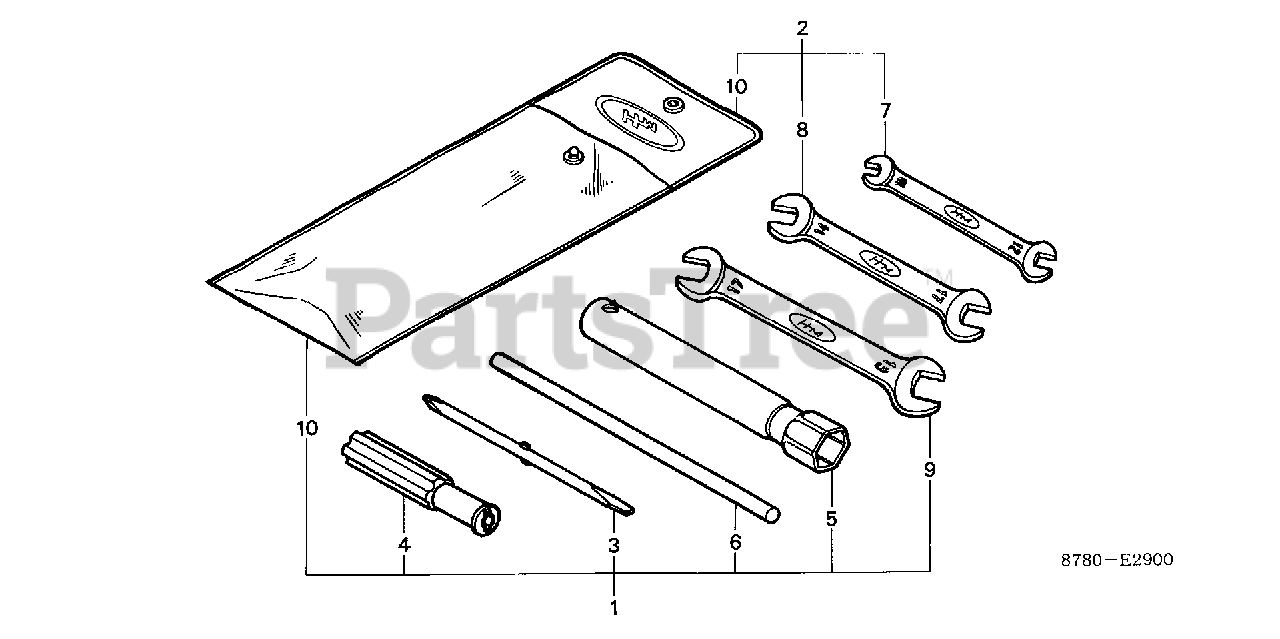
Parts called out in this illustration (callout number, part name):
2	TOOL KIT (N/A: SEE COMPONENTS)
5	WRENCH, SPARK PLUG
6	HANDLE, BOX WRENCH
7	SPANNER (10X12)
8	SPANNER (14X17)
10	BAG, TOOL
